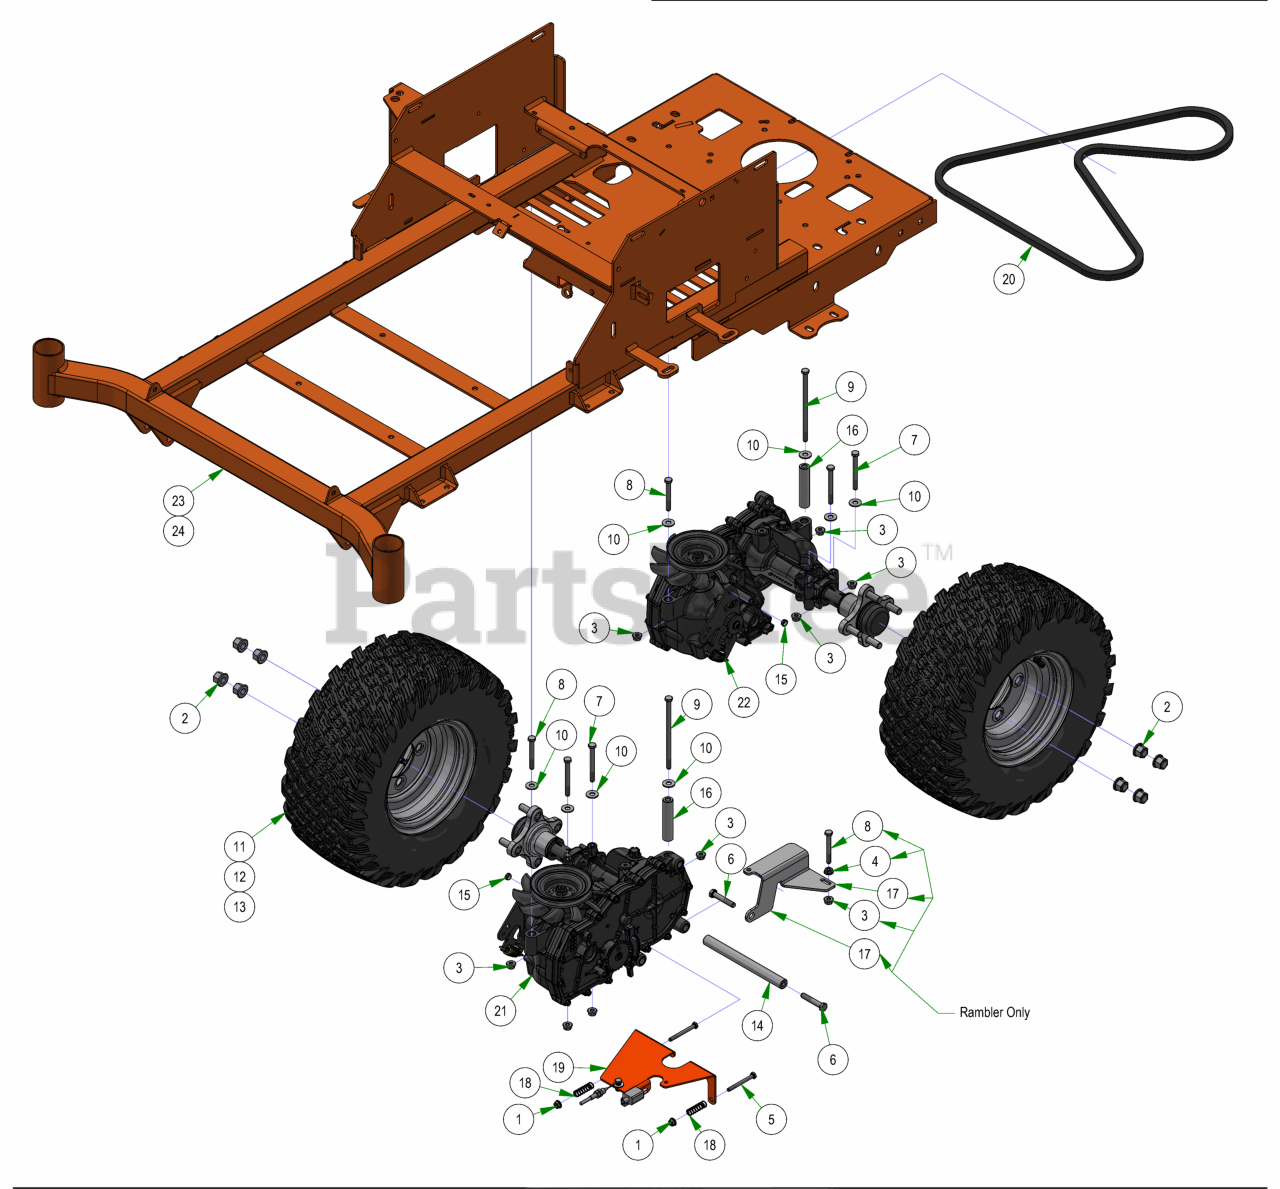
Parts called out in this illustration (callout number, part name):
1	1/4-20 NYL INSERT FLANGE LOCKNUT ZINC
2	Acorn Lug Nut
3	5/16-18 NYLON INSERT FLANGE LOCKNUT ZINC
4	5/16-18 HEX SERRATED FLANGE NUT HARD/ZINC
5	1/4-20 X 2-1/2 HEX CAP SCREW (GR.2) ZINC
6	3/8-16 X 2 HEX CAP SCREW (GR.5) ZINC
7	5/16-18 X 3 HEX CAP SCREW (GR.5) ZINC
8	5/16-18 X 2-1/2 HEX CAP SCREW (GR.5) ZINC
9	5/16-18 X 6 HEX CAP SCREW (GR.5) ZINC
10	5/16 USS FLAT WASHER (7/8 OD) ZINC
11	Rear Wheel Assy Reaper (18x8.5-8)
12	18x9.50-8 Tire and Wheel - Black Wheel
13	Rear Wheel Assy Reaper (18x9.5-8)
14	2017 Transaxle Spacer-MZ
15	Drive Arm Transaxle Spacer
16	2017 Transaxle Spacer
17	Ogura Clutch Belt Retainer
18	Brake Spring
19	MZ Brake Plate Assembly w/ Brake Cable
21	2017 EZT -Right -MZ Models
22	2017 EZT -Left -MZ Models
23	2025 MZ 42-48 Frame
24	2025 MZ-Avenger 54-60 Frame
